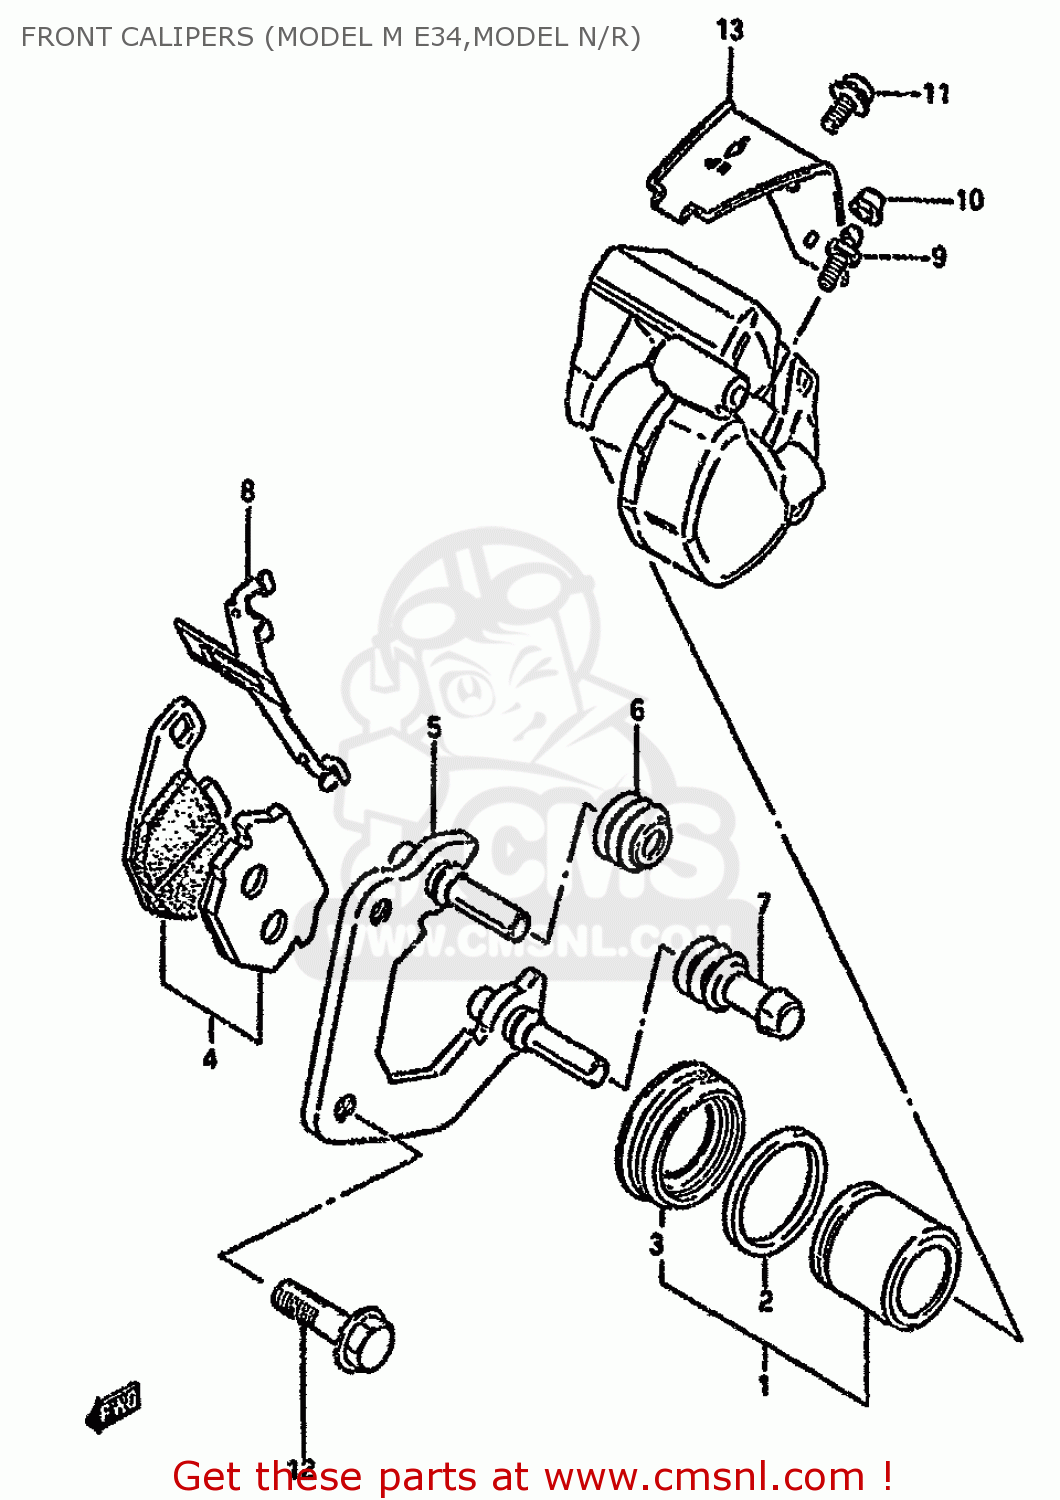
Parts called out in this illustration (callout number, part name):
1	PISTON SET
2	SEAL,PISTON
3	BOOT,PISTON
4	PAD SET (NAS)
5	CARRIER,L
6	BOOT,AXLE
7	INSULATOR,AXLE
8	SPRING,PAD
9	BLEEDER
10	CAP,BLEEDER PLUG
11	SCREW
12	BOLT
13	PROTECTOR,CALIPER
14	SPRING,PAD NO.1
15	SPRING,PAD
16	BREATHER
17	CAP,BLEEDER PL
18	SCREW
19	BOLT 8X30
20	PROTECTOR,CALIPER
